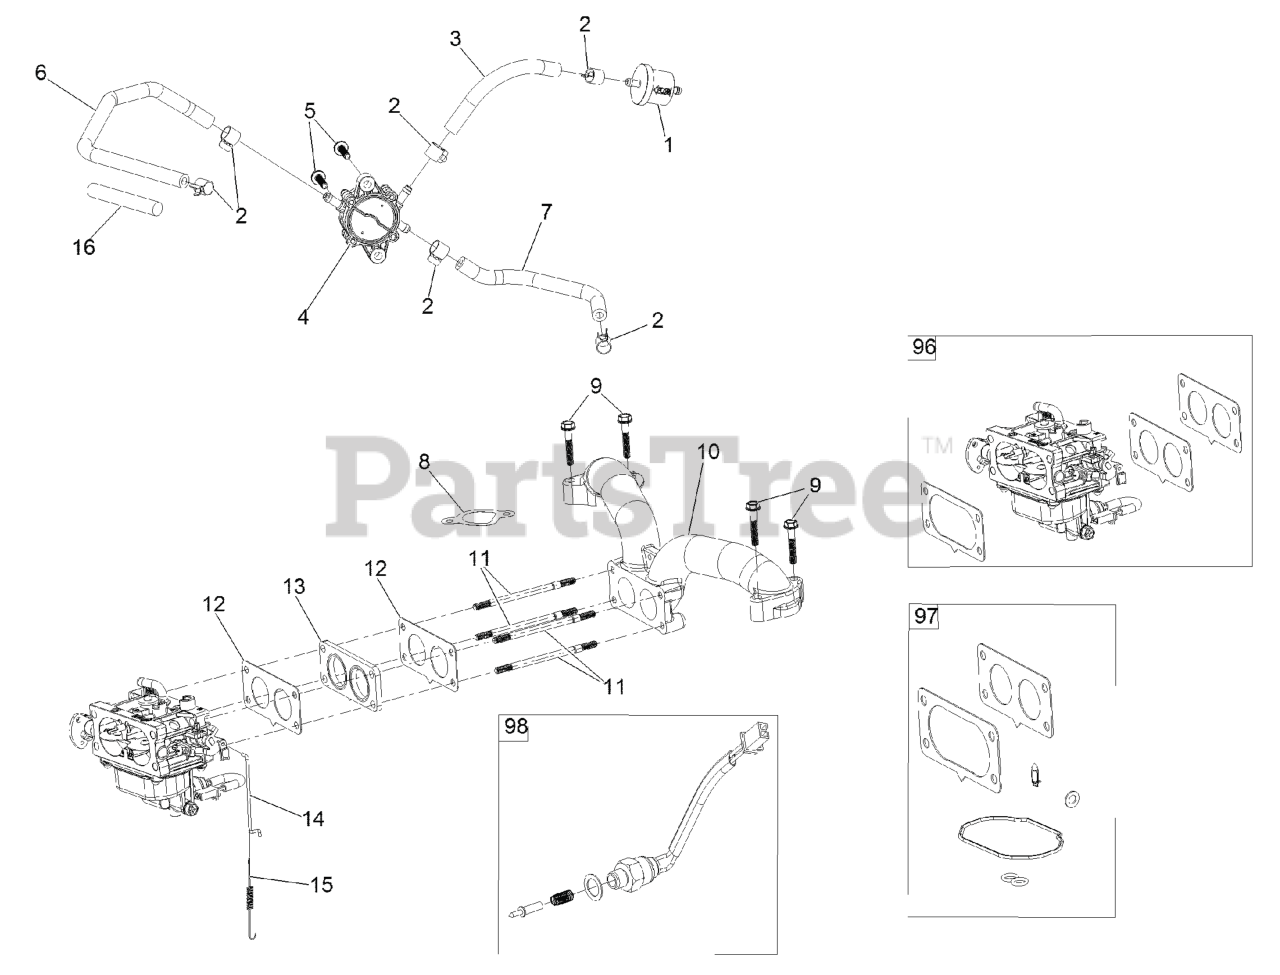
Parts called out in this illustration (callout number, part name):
1	FILTER-FUEL
2	CLAMP-FUEL LINE
3	LINE-FUEL
4	PUMP-FUEL
5	SCREW-HHF
6	HOSE-FUEL
7	HOSE-FUEL
8	GASKET-INTAKE
9	SCREW-HHF
10	MANIFOLD-INTAKE
12	GASKET-CARBURETOR
13	INSULATOR-CARBURETOR
14	LINKAGE-THROTTLE
15	SPRING-RETURN, THROTTLE
16	SLEEVE-FUEL LINE PROTECTO
96	CARBURETOR REPLACEMENT KI
97	CARBURETOR REPAIR KIT
98	SOLENOID KIT
